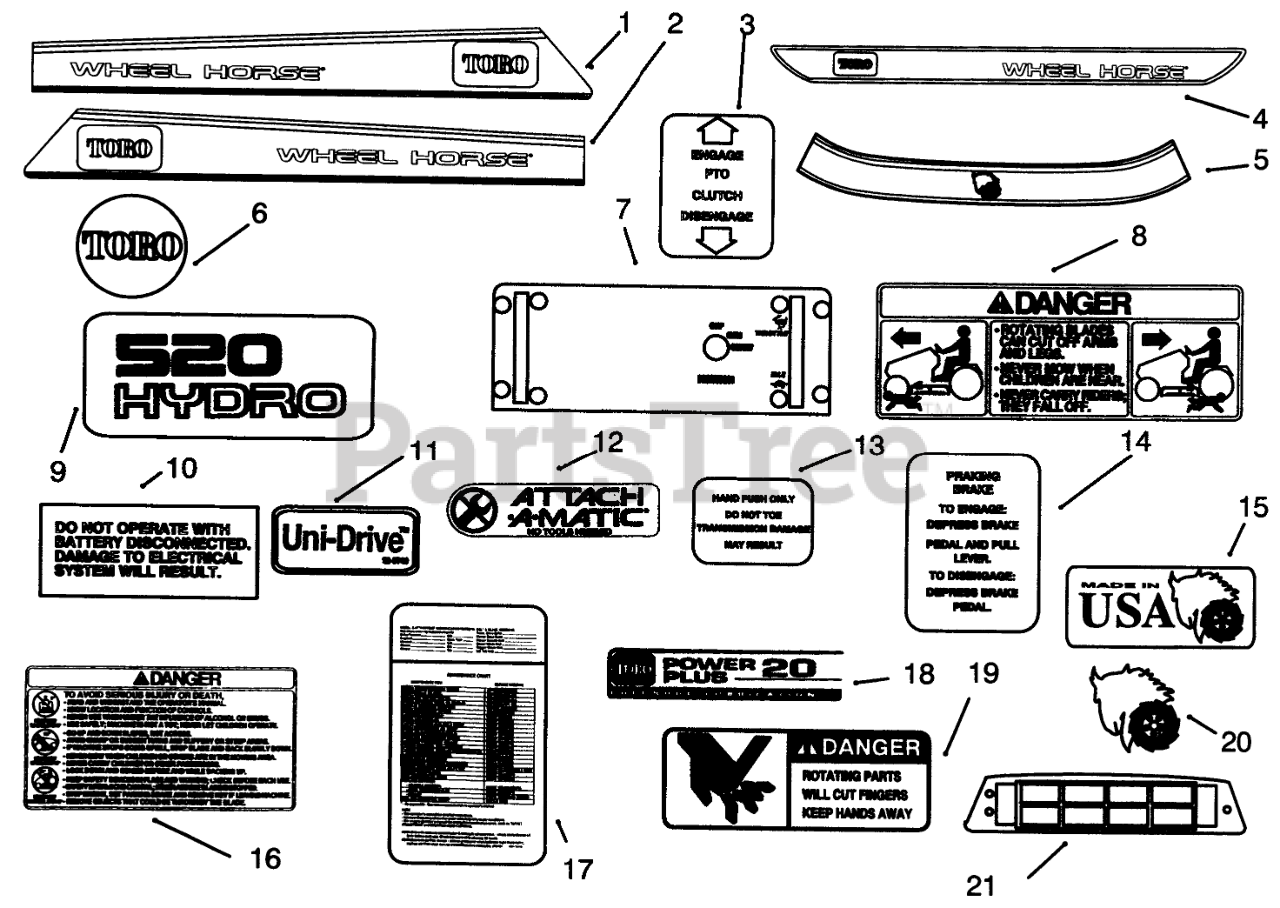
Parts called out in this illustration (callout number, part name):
1	DECAL - RH HOOD TOP
2	DECAL - LH HOOD TOP
3	DECAL PTO CLUTCH
4	DECAL - REAR FENDER
5	DECAL-FRONT HOOD, TOP
6	NAME-PLATE TORO LOGO
7	DECAL-FRONT PANEL
8	DECAL-DANGER
9	Decal-520 Hydro
10	DECAL ELECT SYSTEM
11	Decal-Unidrive
12	DECAL-ATTACH A-MATIC
13	DECAL-DO NOT TOW
14	DECAL-PARKING BRAKE
15	DECAL - USA
16	DECAL - DANGER
17	Decal-Maintenance
18	DECAL-PWR PLUS 20 PL
19	DECAL - DANGER
20	PLATE - LOGO WHL HORSE
21	DECAL-IND LIGHTS
